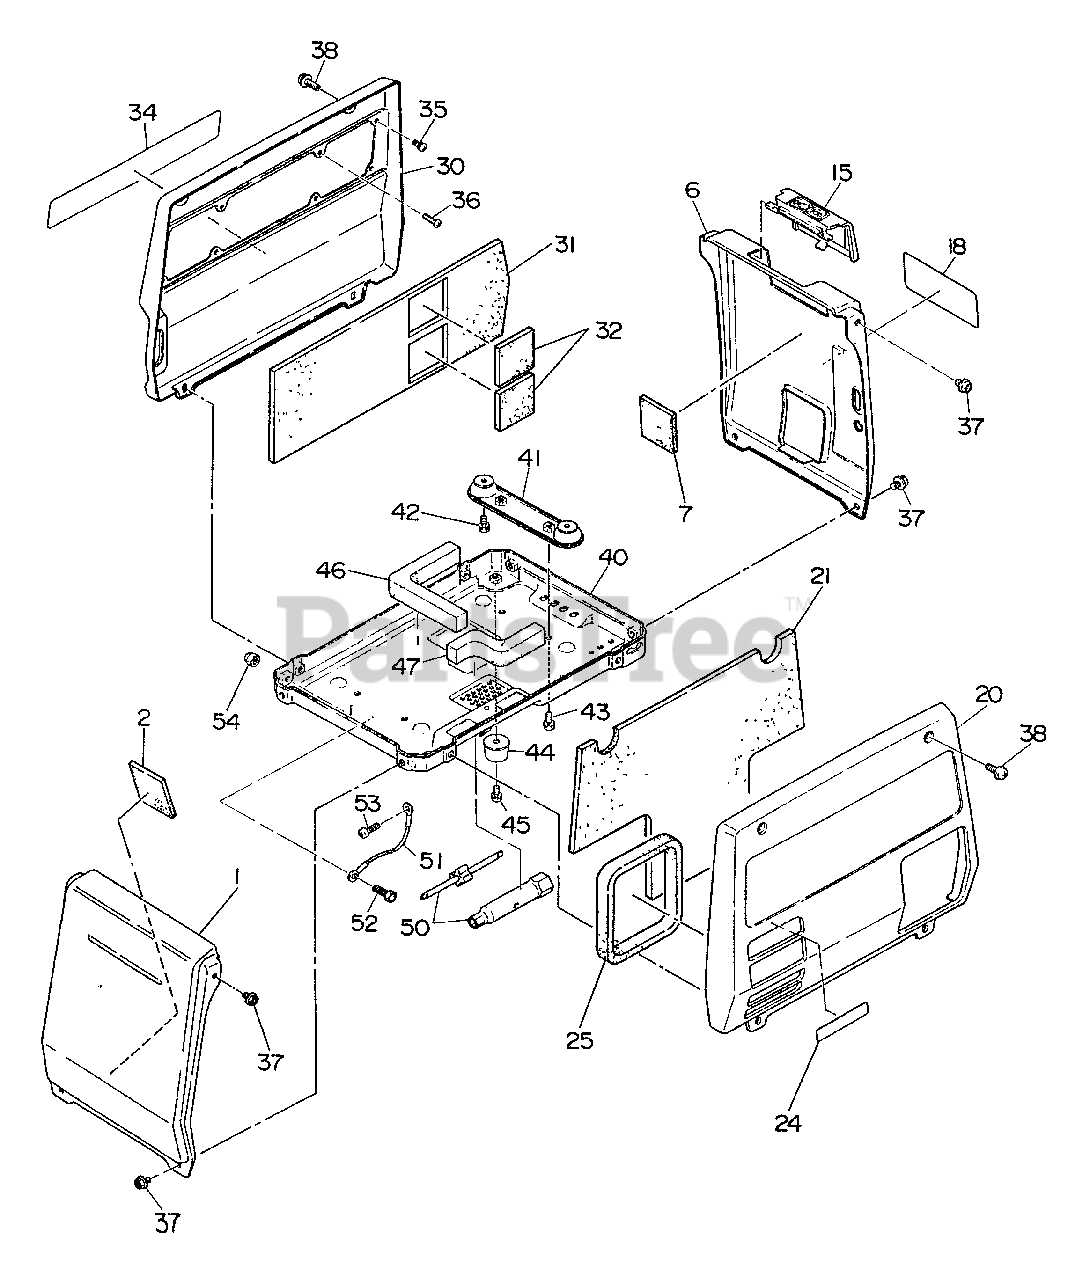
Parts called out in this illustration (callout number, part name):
1	FRONT COVER ASSY
2	RUBBER PLATE 1
6	COVER ASSY - REAR
7	RUBBER PLATE 1
15	COVER
18	LABEL - SPEC. for 60Hz-120V
20	SIDE COVER ASSY - RIGHT
21	SPONGE (R)
24	LABEL - SPARK ARRESTER
25	SEAL, EXHAUST
30	SIDE COVER ASSY - LEFT
31	SPONGE (L)
32	RUBBER PLATE 1
34	LABEL - TRADE MARK
35	SCREW
36	SCREW -- TAPPING
37	BOLT - FLANGE
38	FLANGE SCREW
40	BASE PLATE ASSY
41	MOUNT ASSY - A
42	BOLT
43	BOLT
44	MOUNT ASSY - B
45	SCREW
46	SEAL 1(BASE)
47	LABEL - GENERATOR
50	TOOL KIT
51	GROUND LEAD KIT
52	BOLT
53	SCREW
54	NUT - CROWN
